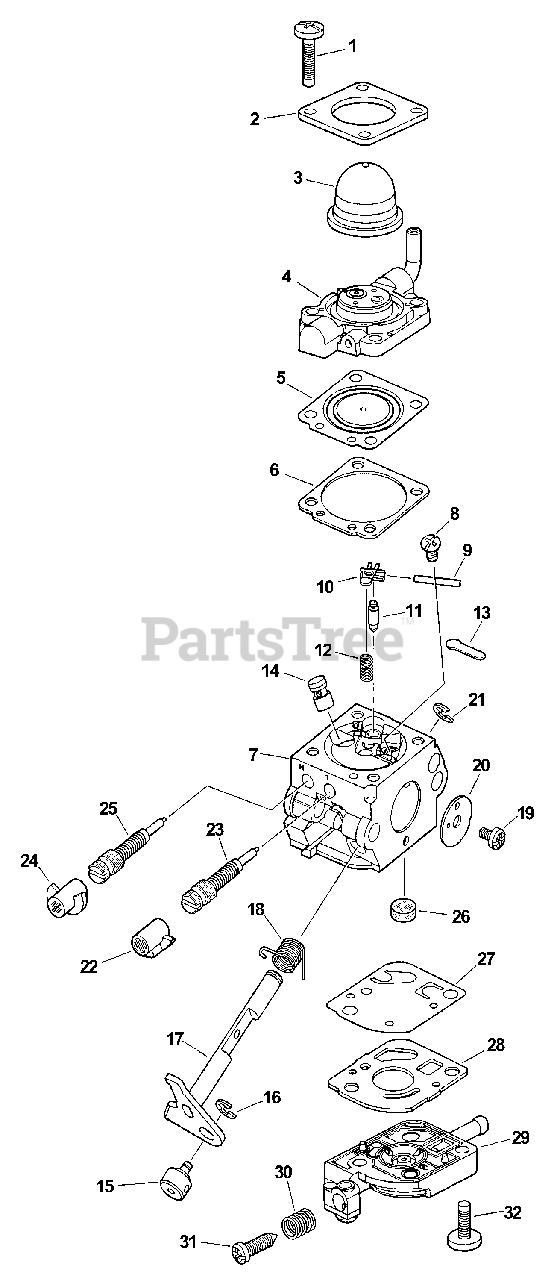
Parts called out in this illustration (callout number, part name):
2	RETAINER, PURGE BULB
3	BULB, PURGE
4	BODY ASSY, PURGE
5	DIAPHRAGM, METERING
6	GASKET, METERING
7	BODY, CARBURETOR
9	PIN, METERING LEVER
10	LEVER, METERING
11	VALVE, INLET NEEDLE
12	SPRING, METERING LEVER
13	PLUG, WELCH
14	NOZZLE, CHECK VALVE
17	SHAFT, THROTTLE
18	SPRING, THROTTLE RETURN
20	VALVE, THROTTLE
22	CAP, LIMITER - WHITE
23	NEEDLE, MIXTURE
24	CAP, LIMITER - RED
25	NEEDLE, HIGH SPEED
26	STRAINER
29	COVER, FUEL PUMP
31	SCREW, THROTTLE ADJUST
